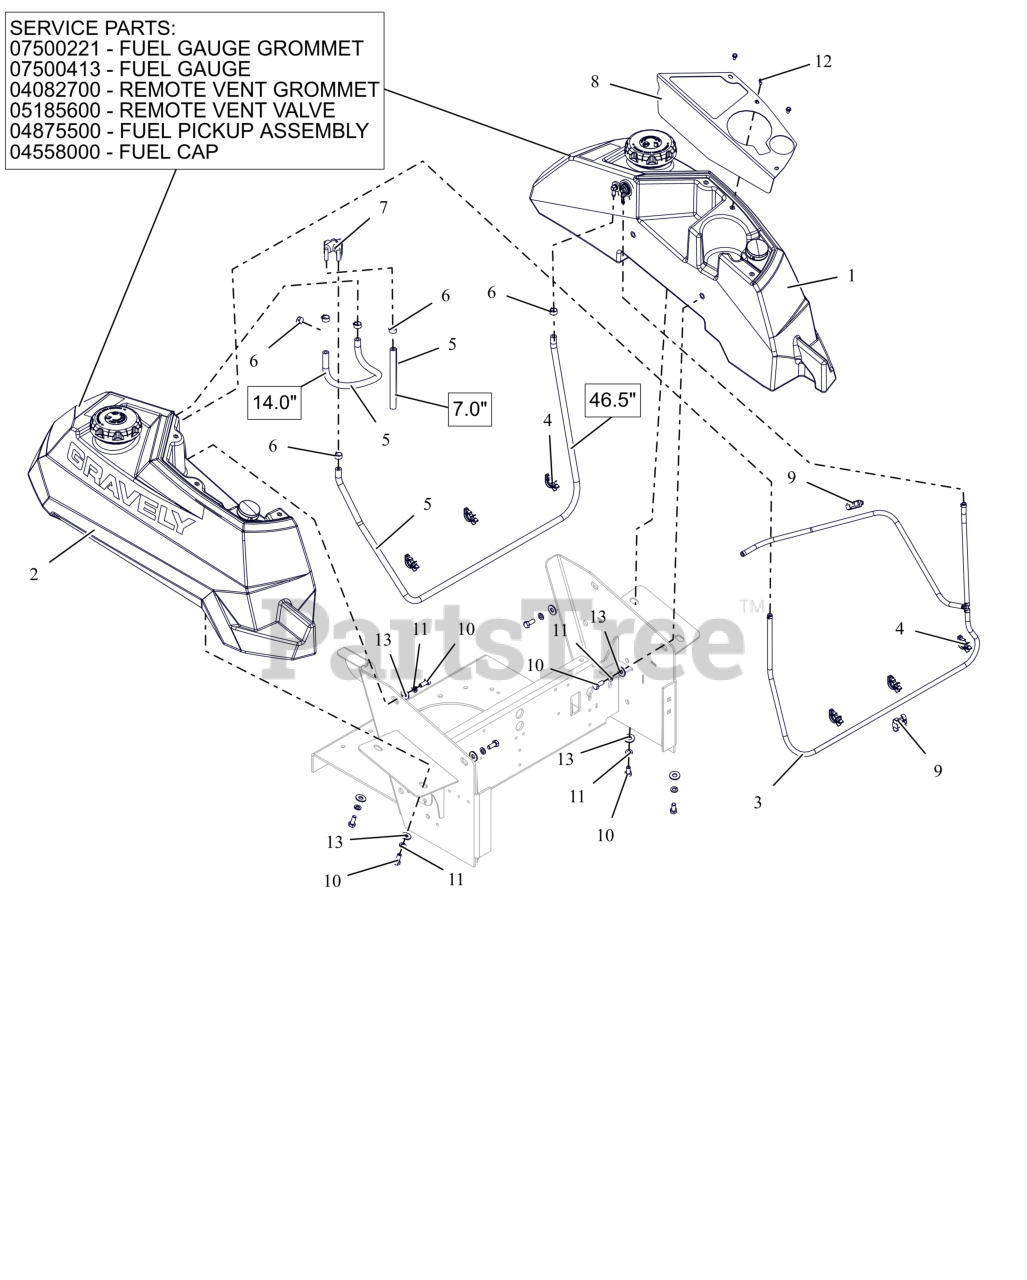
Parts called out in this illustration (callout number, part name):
1	ASM, LH - PT100 FUEL TANK
1	GROMMET, FUEL GAUGE
1	GAUGE, REMOTE SEALED FUEL
1	GROMMET, REMOTE VENT NITRILE
1	VALVE, COMBINATION VENT 3/16
1	ASSM,LRG TANK FUEL PICKUP LINE
1	CAP, FUEL VENTIN AUTOLOCK
2	ASM, RH - PT100 FUEL TANK
2	GROMMET, FUEL GAUGE
2	GAUGE, REMOTE SEALED FUEL
2	GROMMET, REMOTE VENT NITRILE
2	VALVE, COMBINATION VENT 3/16
2	ASSM,LRG TANK FUEL PICKUP LINE
2	CAP, FUEL VENTIN AUTOLOCK
3	ASM, VAPOR LINE
4	WIRE CLIP
5	HOSE, .25 LOW-PERM BULK GAS
6	CLAMP, FUEL LINE
7	VALVE, FUEL
8	PT100 CUPHOLDER PANEL - RED
9	CLIP, T, .38-.50
10	BLT,HEX .31-18X.75 G5 ZCC
11	WSHR,LK-REG .312X.078 ZCC
12	SCR-MCH 10-24X.38 HWHSTAINLESS
13	WSHR,FLT .375X.875X.083 ZCC
